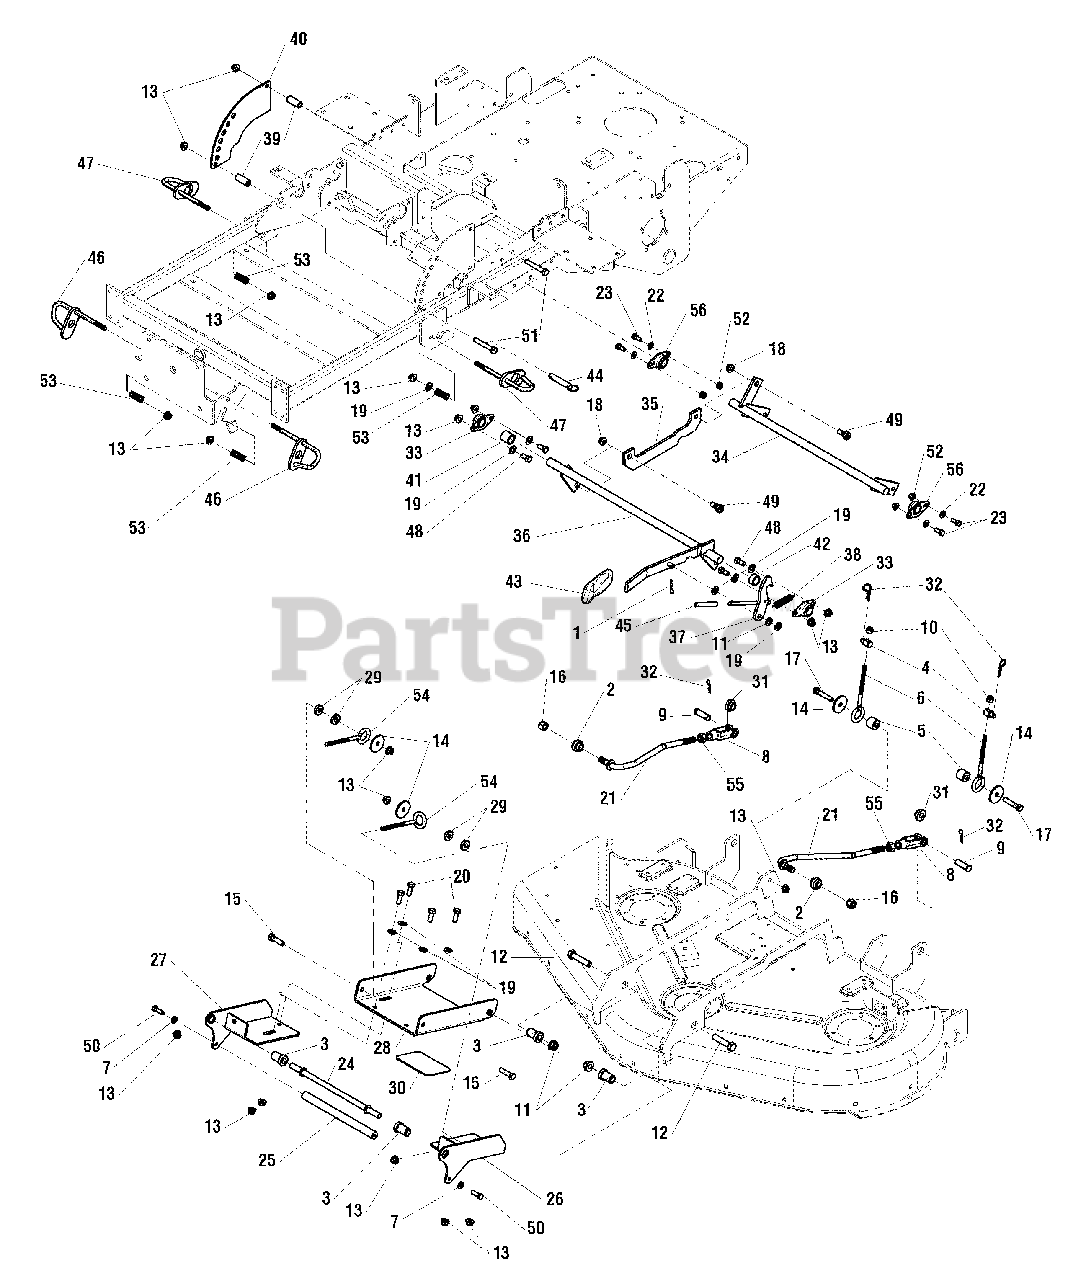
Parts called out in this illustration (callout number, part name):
1	PIN, Cotter, 1/8" X 3/4"
2	BUSHING, REAR QUICK TACH
3	SPACER, .53 X 1.00 X 1.44
4	ADJUSTER, BRAKE LINKAGE
5	SPACER, .39 X 1.00 X .88
6	EYE BOLT, 3/8-16 X 6" , 1" EYE
7	PIN, HAIR, .0915 X 1-7/8
8	CLEVIS , 1/2-20, STEEL
9	PIN CLEVIS 1/2" X 1-1/4"
10	NUT, 3/8-16 HEX NYLON LOCK
11	WASHER, WAVE, M10
12	BOLT, 1/2-20 X 2-1/2" GD5 CZ
13	NUT, 3/8-16 HEX NYLOCK FLANGE
14	WASHER, .41 X 1.75 X .14
15	BOLT, 3/8-16 X 1-1/2" GD5 CZ
16	NUT, Hex, Nylon Lock, 1/2-20
17	BOLT, 3/8-16 X 2, GD5, CZ
18	NUT, 3/8-16 HEX SERRATED FLANGE
19	WASHER, 3/8 SAE
20	BOLT, 3/8-16 X 1" GD5 CZ
21	ROD, DECK LIFT, LINKAGE
22	WASHER, 5/16" SAE
23	BOLT, 5/16-18 X 1" GD5
24	SHAFT, HANGER
25	SHAFT, HANDLE, DECK SUPPORT
26	WELD, DECK HANGER, LH
27	WELD, DECK HANGER, RH
28	PLATE, DECK HANGER SUPPORT
29	SPACER, .39 X 1.00 X .25
30	SAFETY WALK, 4.50 X 3.50
31	BUSHING, DECK SUPPORT
32	HAIRPIN
33	BEARING, BRONZE FLANGE 3/4"
34	WELD, DECK LIFT HANGER REAR
35	LINK, DECK LIFT SHAFT
36	WELD, DECK HEIGHT SHAFT
37	WELD, DECK LOCK
38	SPRING, EXTENSION
39	SPACER, .63 X .39 X 1.50
40	PLATE, INNER DECK HEIGHT
41	SPACER, .76 X 1.00 X 1.00
42	SPACER, .76 X 1.00 X .50
43	GRIP, BLACK FLEXIBLE
44	HITCH PIN, 1/2" X 2-1/2"
45	COVER, VINYL HANDLE
46	WELD, QUICK RELEASE HANDLE, FRONT
47	WELD, QUICK RELEASE HANDLE, REAR
48	BOLT, 3/8-16 X 3/4" GD5 CZ
49	SHOULDER BOLT, 3/8-16 X 1/2 X 3/8
50	BOLT, 5/16-18 X 3/4 GD5
51	BOLT, 3/8-16 X 2-1/2" GD5 CZ
52	NUT, 5/16-18 HEX NYLOCK FLANGE
53	SPRING, COMPRESSION
54	EYE BOLT, 3/8-16 X 5, 2.88THRD, 1EYE, CZ
55	NUT, 1/2-20 HEX JAM
56	BEARING, BRONZE FLANGE, 3/4"
